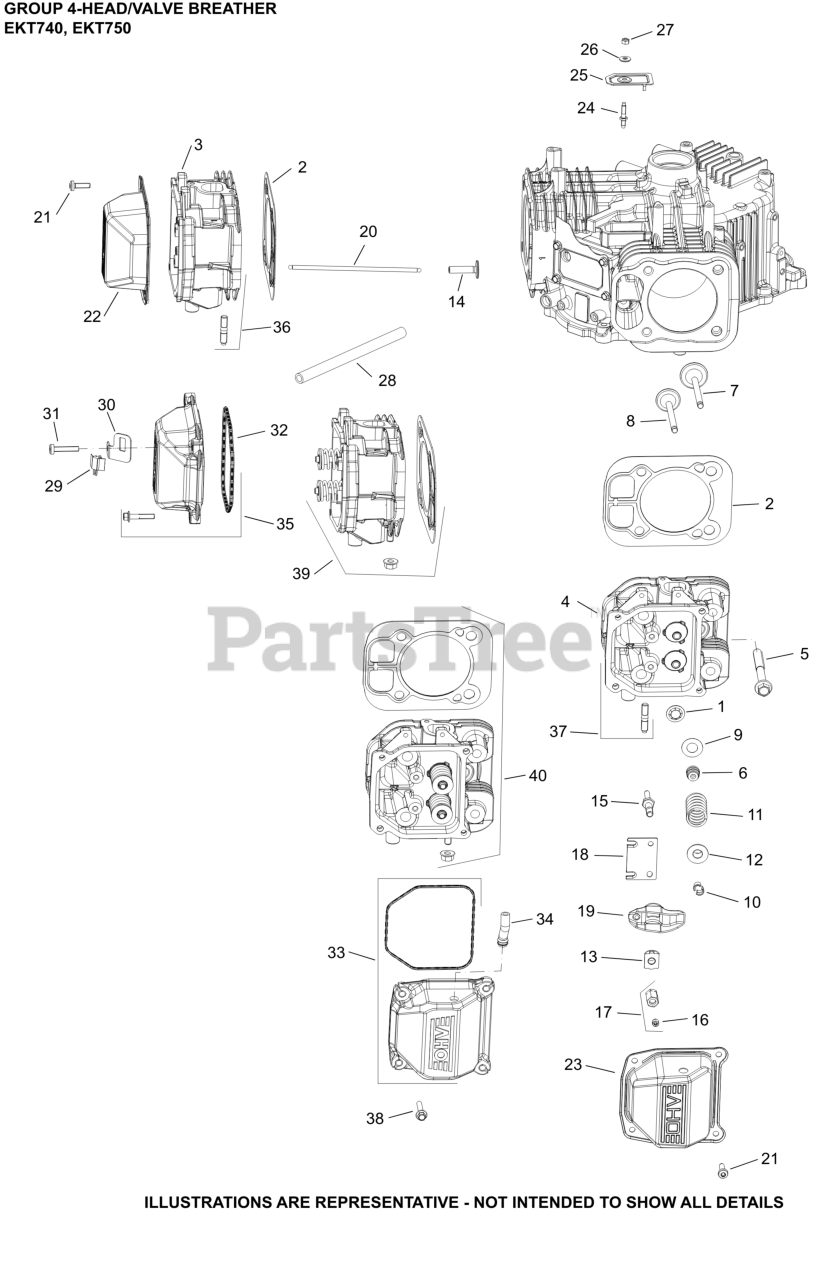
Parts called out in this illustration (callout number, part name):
1	RETAINER, VALVE GUIDE (KM)
2	KIT, CYLINDER HEAD GASKET
5	SCREW, HEX FLANGE M10 X 1.5-6g X 90mm
6	SEAL, VALVE BAND
7	VALVE, INTAKE
7	VALVE, INTAKE (.25) - (#2401702S)
8	VALVE, EXHAUST
8	VALVE, EXHAUST (.25)
9	SPACER (.010")
10	KIT, RETAINER
11	SPRING VALVE
12	CAP, VALVE SPRING
13	PIVOT, ROCKER ARM
15	STUD, ROCKER
16	SCREW, SET
17	HEX NUT ASSEMBLY
18	PLATE, GUIDE
19	ARM, ROCKER
20	ROD, PUSH
25	COVER, BREATHER REED
26	WASHER, SEALING
27	NUT, LOCK M5X.8
28	HOSE, BREATHER
32	O-RING (YELLOW), VALVE CO
33	KIT,BREATHER VALVE COVER (PLASTIC)
34	HOSE, FP-USE 32 326 07-S(PLASTIC COVERS)
35	KIT, VALVE COVER-PLAIN (PLASTIC)
38	SCREW, HEX FLANGE (M6 X 31.625 DOG PT)
39	KIT, #1 CYLINDER HEAD
40	KIT, #2 CYLINDER HEAD
